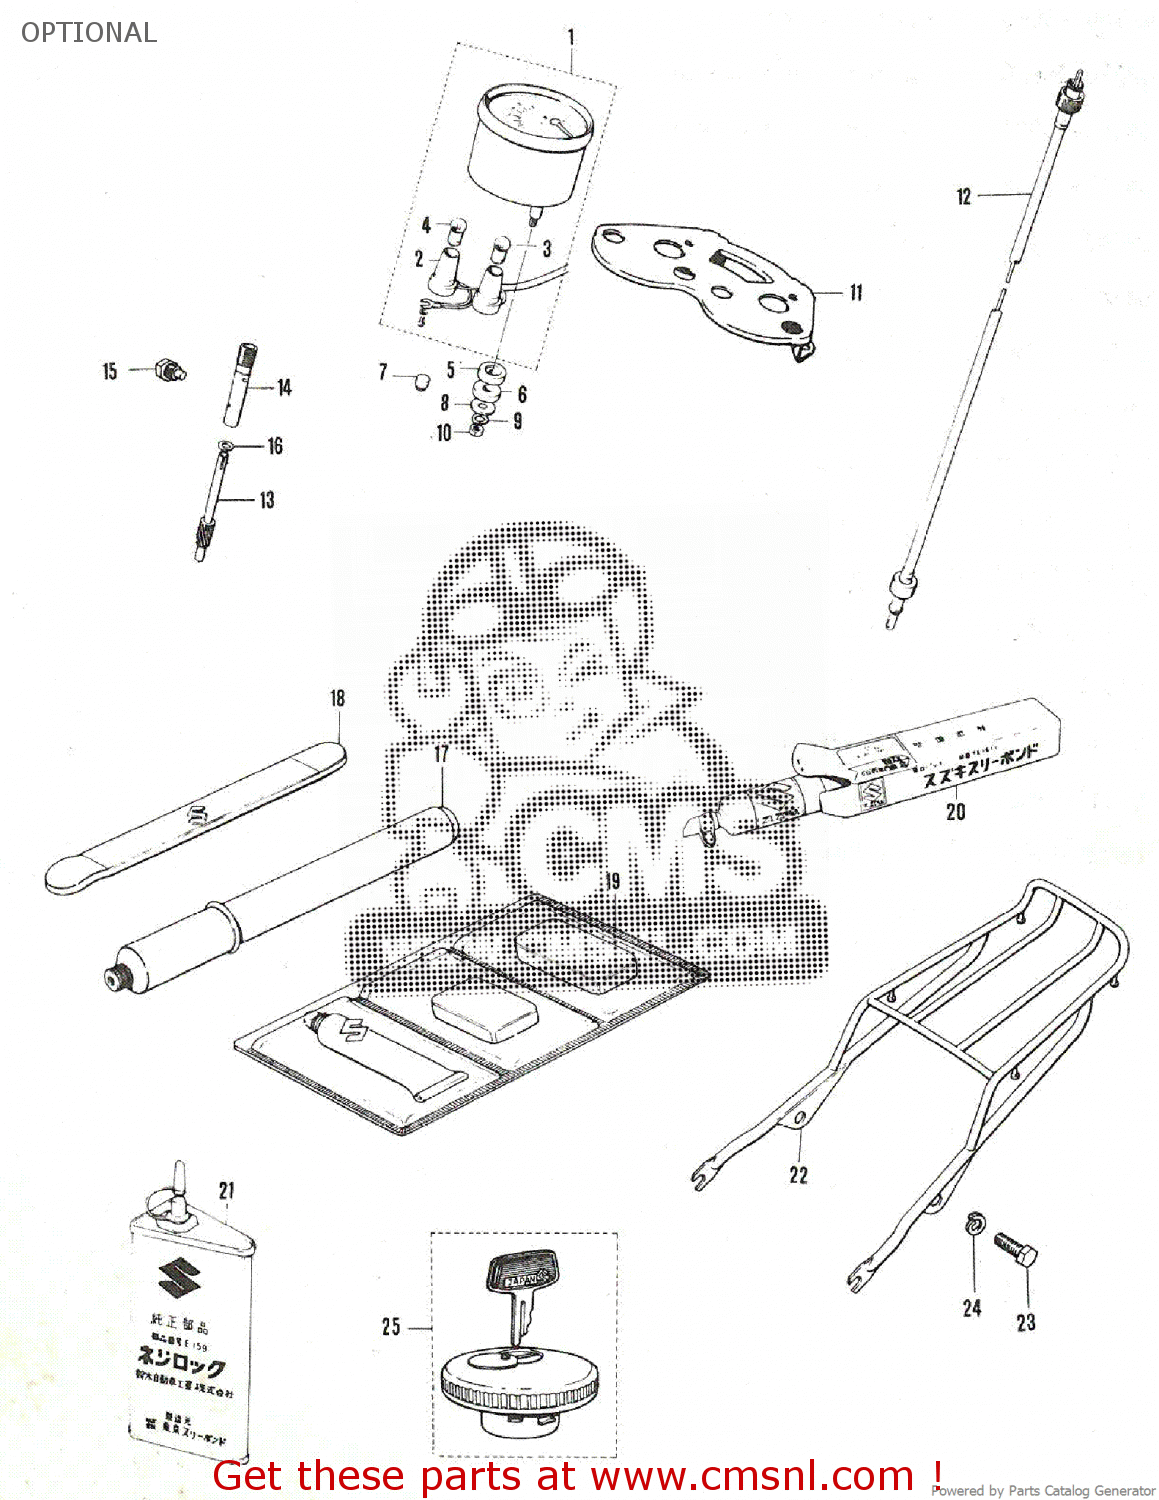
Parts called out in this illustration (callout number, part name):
1	TACHOMETER ASSEMBLY
2	SOCKET,METER
3	BULB(6V/3W)
4	BULB(6V1.7W,STANLEY,A61A)
5	CUSHION,METER
6	CUSHION
7	METER REAR CUSHION
8	WASHER (5.5X18X1.6)
9	LOCK WASHER
10	NUT
11	BRACKET,METER
12	CABLE ASSEMBLY,TACHOMETER
13	GEAR,TACHOMETER DRIVEN
14	SLEEVE, DRIVEN GEAR
15	BOLT(6X12)
16	WASHER(8X13.7X1)
17	INFLATOR, AIR
18	LEVER,TIRE
19	TUBE REPARING TOOL
20	LIQUID GSKT 150G BLACK
21	THREAD CEMENT
22	CARRIER
23	SMALL HEAD HEXAGON BOLT
24	LOCK WASHER
25	FUEL TANK CAP
